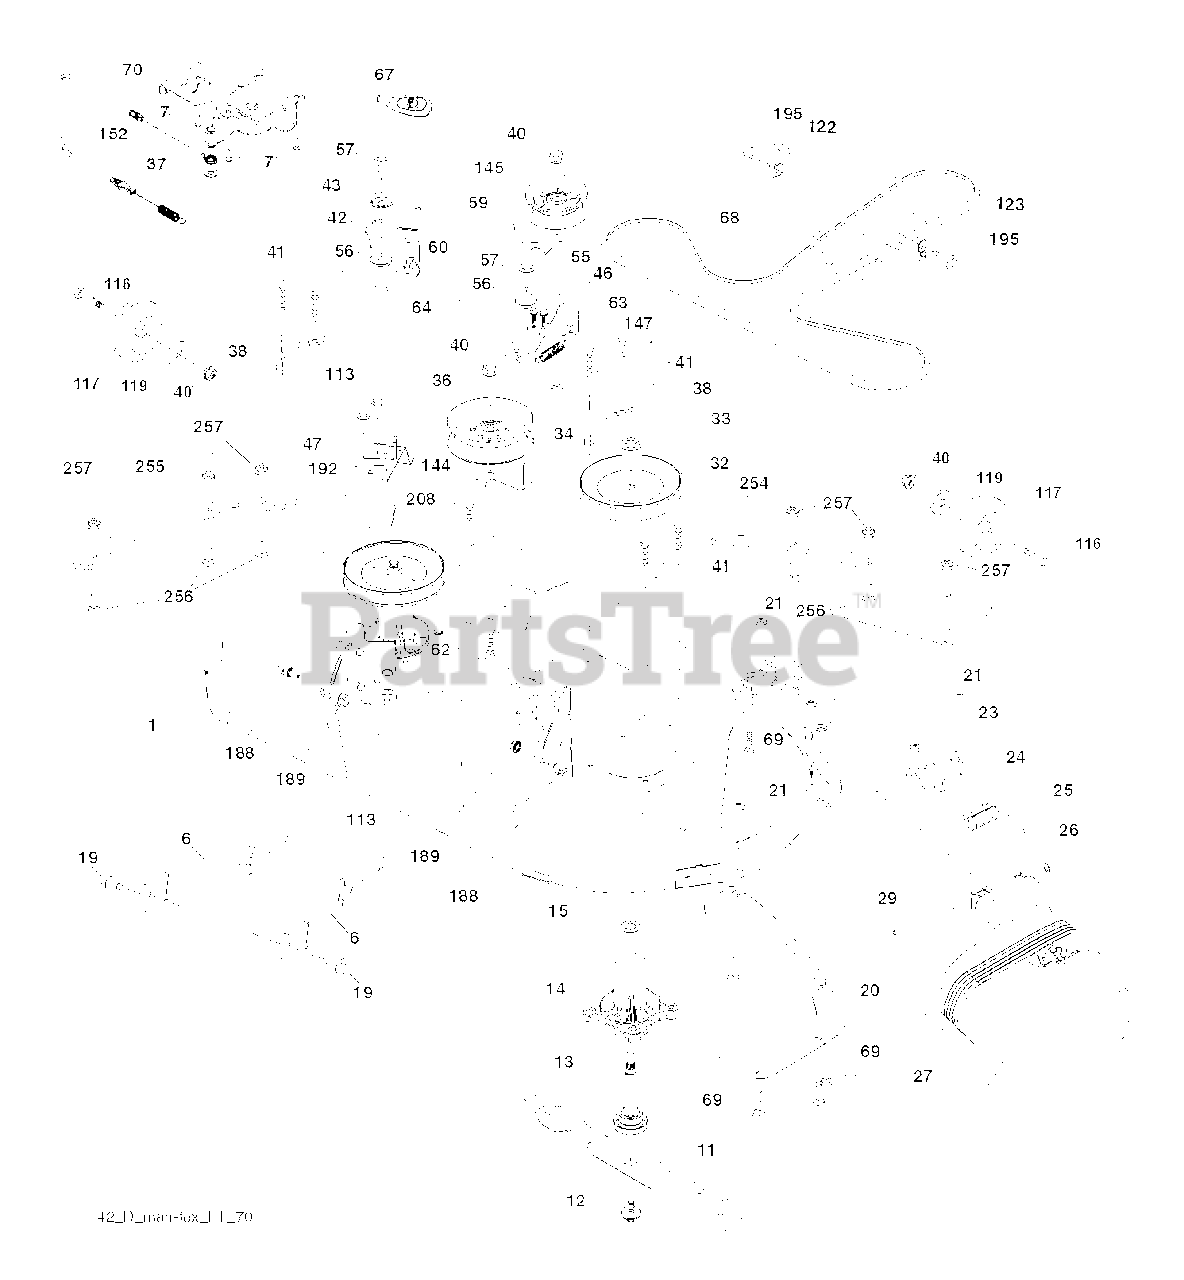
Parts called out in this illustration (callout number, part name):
1	Mower Deck Assembly, 42"
6	ARM.SUSPENSION.MOWER.R
7	SCREW.#10 X 0.750.BOS (2 2)
11	42" HI-LIFT BLADE
12	Screw, 7/16 X 20 X 1"
13	SHAFT.ASM.MDRL.N/GREASE.38
14	HOUSING.MANDREL.4PT.
19	BOLT.SHOULDER
20	BAFFLE.VORTEX
21	LOCKNUT
23	BRKT.DEFLECTOR.38"2005+
24	CAP-SLEEVE LT
25	SPRING.TORSION.DEFLECT
26	NUT PUSH M
27	SHIELD.DEFLECTOR.MOWER.42"BLAC
29	ROD.HINGE
32	PULLEY.MANDREL.5.438.PD
33	NUT.FLANGE.LOCK.TOP
34	BOLT.3/8-16X1.50
36	PULLEY.IDLER.2006
38	KEEPER.BELT.MANDREL.PULLEY
40	NUT LOCK FLG 3/8-16 UNC
41	Hex Washer Head Bolt, .313-18 X 1.19
42	SPRING.TORSION.BRAKE
43	SRPING.TORSION.RETAINE
46	SCREW.1/4-20X5/8
47	BRKT.CLUTCH.CABLE
55	IDLER.ARM.42"
56	SPACER.RETAINER
57	SCREW 3/8-16X1
59	GUARD, BELT
60	ARM BRAKE MOWER
62	BOLT
64	LINKAGE.BRAKE.ASM.ZINC
67	HANDLE.CLUTCH.CABLE.LT
68	BELT.DECK.DRIVE.42"
69	BOLT
70	CLUTCH.ASM.MANUAL.LT.PRED
113	BOLT.5/16HEX.WHS.HD
116	BOLT M
117	WHEEL.GAGE.HALF.SPOKED
119	WASHER
122	KEEPER BELT ENGINE LH
123	KEEPER BELT RH
144	KEEPER.BELT.MOWER
145	PULLEY.IDLER.48"PRIMARY
147	RETURN SPRING
152	CABLE.MECHANICAL.CLUTCH
188	STUD.FASTNER.W/ANTI-ROTATE
189	NUT LOCK HEX FLANGE 5/16-18
192	BRKT.BRAKE.STAND.LH.
195	SCREW, 3/8-16X3/4
208	SCREW 3/8-16X1/2
254	Front Reinforcement Plate, 42" Deck.Ftx498
255	Side Reinforcement Plate, 42"
256	RHSNB, 1/4-20 X 1, GR5
257	NUT T
